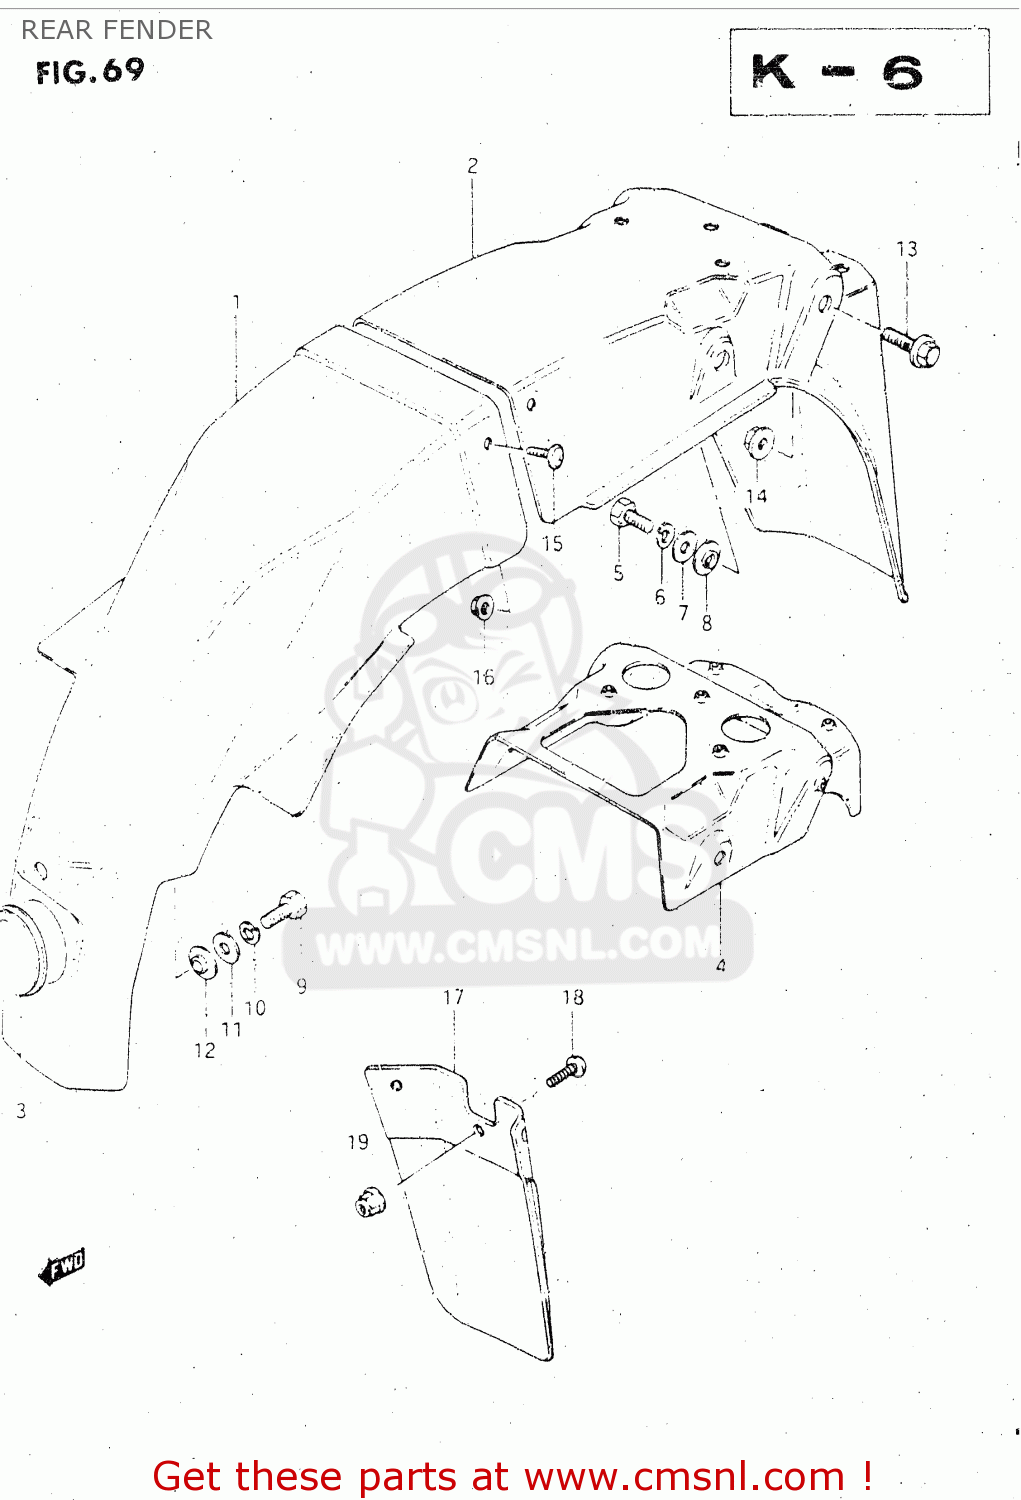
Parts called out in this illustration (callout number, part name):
1	BODY,REAR FENDER,FRONT
2	FENDER, REAR
3	GROMMET,REAR FENDER,FRONT
4	REINFORCEMENT,REAR
5	BOLT
6	LOCK WASHER
7	WASHER
8	WASHER
9	BOLT, UPPER
10	WASHER,LOCK
11	WASHER 6MM
12	WASHER
13	BOLT
14	NUT
15	SCREW
16	NUT
17	EXTENSION
18	SCREW
19	NUT
